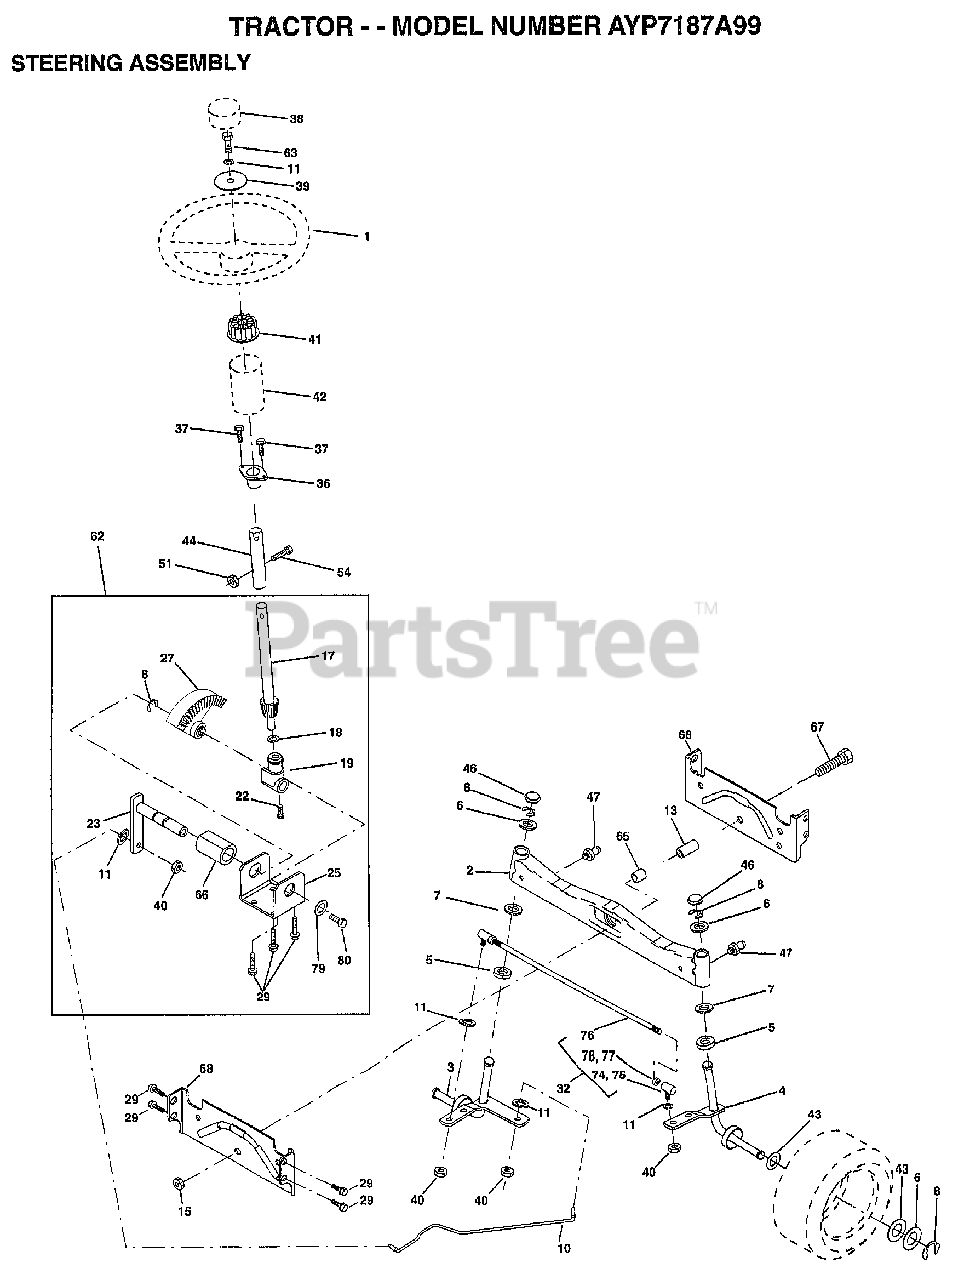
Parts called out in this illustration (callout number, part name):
1	WHEEL STR AYP BLK
3	"SPINDLE ASM,LH"
4	"SPINDLE ASM,RH"
5	WASHER .T
6	WASHER
7	WASHER
8	RING
10	LINK.DRAG
11	LOCKWASHER
13	BEARING.FRT.SPACER.AXLE
15	"NUT-LOC,FLANGE LT"
17	SHAFT ASM STEERIN
18	THRUST WASHER
19	SUPPORT.SHAFT.STEER
22	SCREW.HX.WSH.HD
23	SHAFT.ASM.PITMAN
25	BRKT-STEERING
27	GEAR SECTOR
29	SCREW
32	ROD.ASM.TIE.BALL
36	BUSHING.STEERING
37	"SCREW-TT,10-32 FL"
38	CAP STEER AYP
39	WASHER T
40	GRIPCO NUT
41	ADAPTER LT
42	BOOT.STEER.PL
43	WASHER
44	EXT SHAFT STEERIN
46	CAP
47	ZERK M
51	NUT
54	BOLT
62	KIT.STEER.ASM
63	BOLT
65	SPACER AXLE
66	"BEARING-ARM,PITMA"
67	BOLT
68	BRACE AXLE
74	JOINT.RH
75	JOINT.LH
77	NUT
78	NUT
79	WASHER
80	BOLT.HX.NYLON3/8-16X3/
